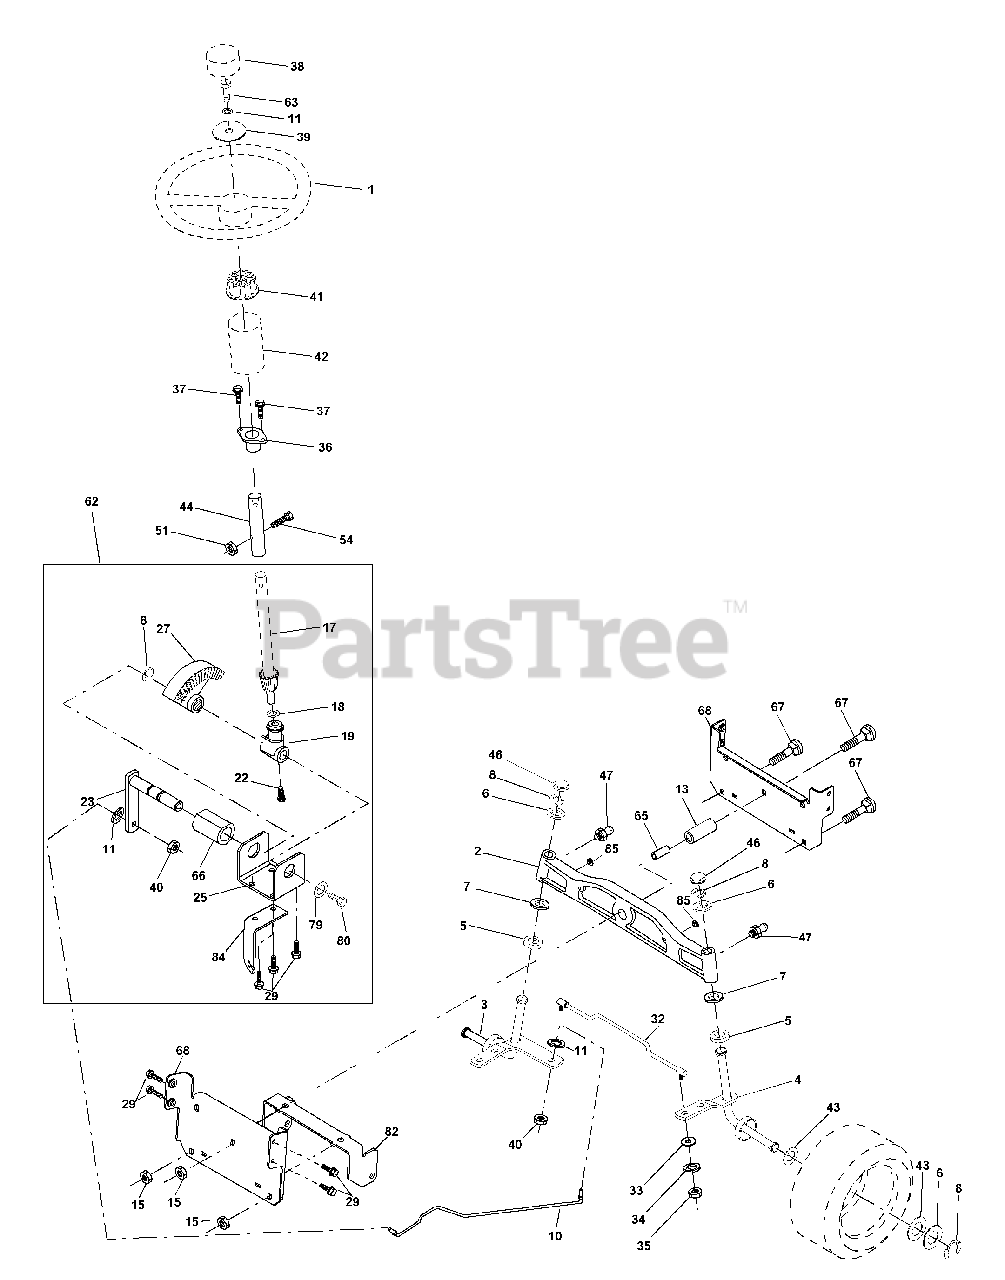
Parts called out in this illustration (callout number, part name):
1	Wheel Steering
2	Axle Cast Lt Machined
3	Spindle Asm LH
4	Spindle Asm RH
5	Bearing Race Thrust Harden
6	Washer 25/32 X 1-5/8 X 16 Ga
7	Washer 27/32 X 1-1/4 X 16 Ga
8	Ring Klip #t5304-75
11	Washer Lock Hvy Hlcl Spr 3/8
13	Spacer Brg Axle Front
15	Nut Hex Flange Lock
17	Shaft Asm Strg
18	Washer Thrust 515x 750x 033
19	Support Shaft
22	Screw Hex Wshhd Torx
23	Shaft Asm Pittman
25	Bracket Steering
27	Gear Sector
29	Screw 3/8-16x3/4
32	Rod Tie Ball J
33	Washer 11/32 x 3/4 x 16 Ga.
34	Washer Lock Hvy Helical 5/16
35	Nut Crown Lock 5/16-18
36	Bushing Strg
38	Insert Cap Strg Wh
39	Washer 13/32 x 1-1/20 x 11 Ga
41	Adaptor Wheel Strg
42	Boot Steering Shaft
43	Washer 25/32 X 1 1/4 X 16 Ga
44	Extension Steering Shaft LR/LT
46	Cap Spindle Fr Top Blk
47	Fitting Grease
51	Nut Lock Hex w/Ins 5/16-18
54	Bolt Fin Hex 5/16-18 Unc x 1-1/4
62	Kit, Steering Assembly Svc
63	Bolt Fin Hex 3/8-16unc x 1 Gr. 5
65	Spacer Brace Axle
66	Bearing Arm Pittman
67	Bolt Rdhd Sqnk 3/8-16 x 2-1/4
68	Axle, Brace
79	Washer 13/32 x 1-1/4 x 12 Ga
80	Bolt Hex Nylon 3/8-16 x 3/4
82	Bracket Susp Chassis Front
83	Lock nut
